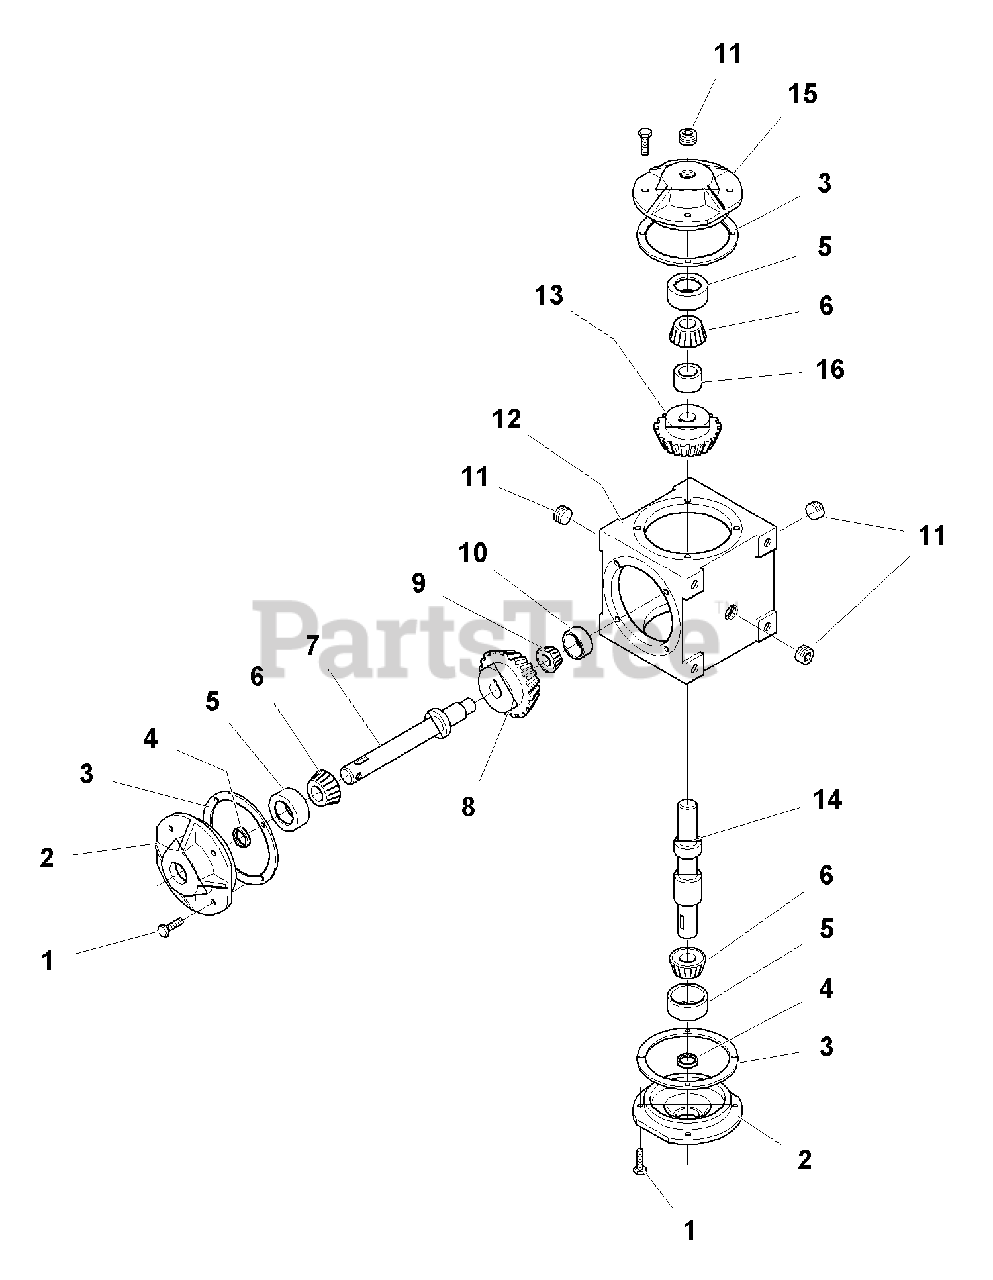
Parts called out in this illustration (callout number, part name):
1	CAPSCREW, Hex Head, Whizlock, 5/16-18 x 3/4
2	CAP, Thru
3	GASKET, 0.015 (Replace with Gasket of Identical Thickness)
3	GASKET, 0.005 (Replace with Gasket of Identical Thickness)
3	GASKET, 0.003 (Replace with Gasket of Identical Thickness)
4	SEAL, Shaft, 1 x 1-1/2 x 5/16
5	BEARING RACE, Cup
6	BEARING, Cone
7	SHAFT
8	GEAR
9	BEARING, Cone
10	BEARING RACE, Cup
11	PLUG, Pipe, Hex Socket Head
12	HOUSING, Gearbox
13	GEAR
14	SHAFT
15	CAP, Blank
16	SPACER (Early Models Only)
